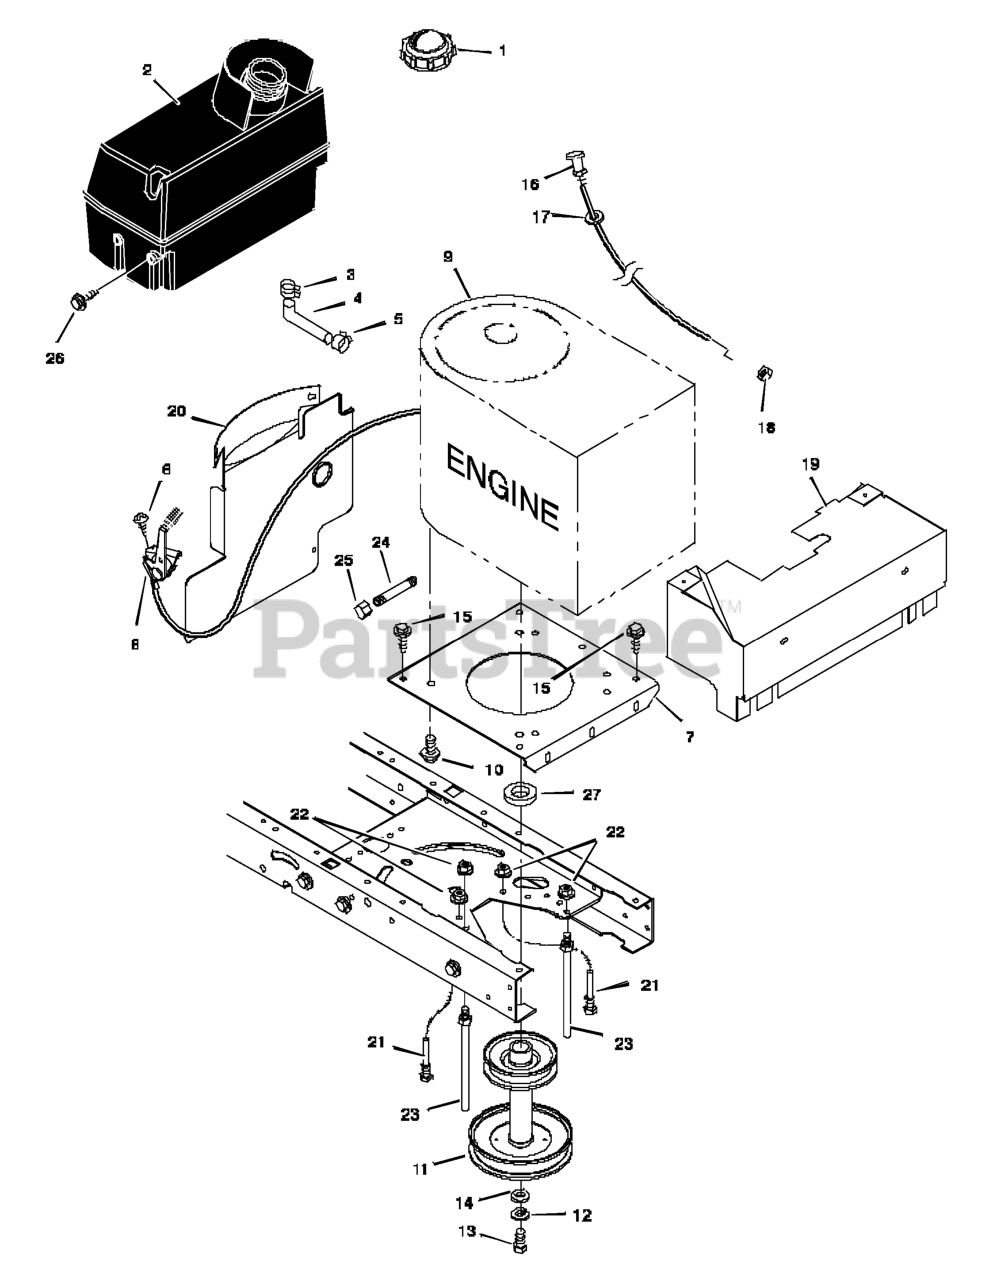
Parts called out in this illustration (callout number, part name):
1	Fuel Cap
2	Fuel Tank
3	Hose Clamp
4	Fuel Line
5	Hose Clamp
7	Plate, Engine
8	Throttle Control
9	Engine *
10	Bolt, Engine Mount
11	Stack Pulley Assembly
12	Lockwasher
13	Bolt, Hex
17	Washer
19	Baffle, Front Engine
20	Baffle, Rear Engine
21	Guide, Belt
22	Nut, Flange
23	Guide, Belt
24	Pipe, Oil Drain
25	Cap, Oil Drain
